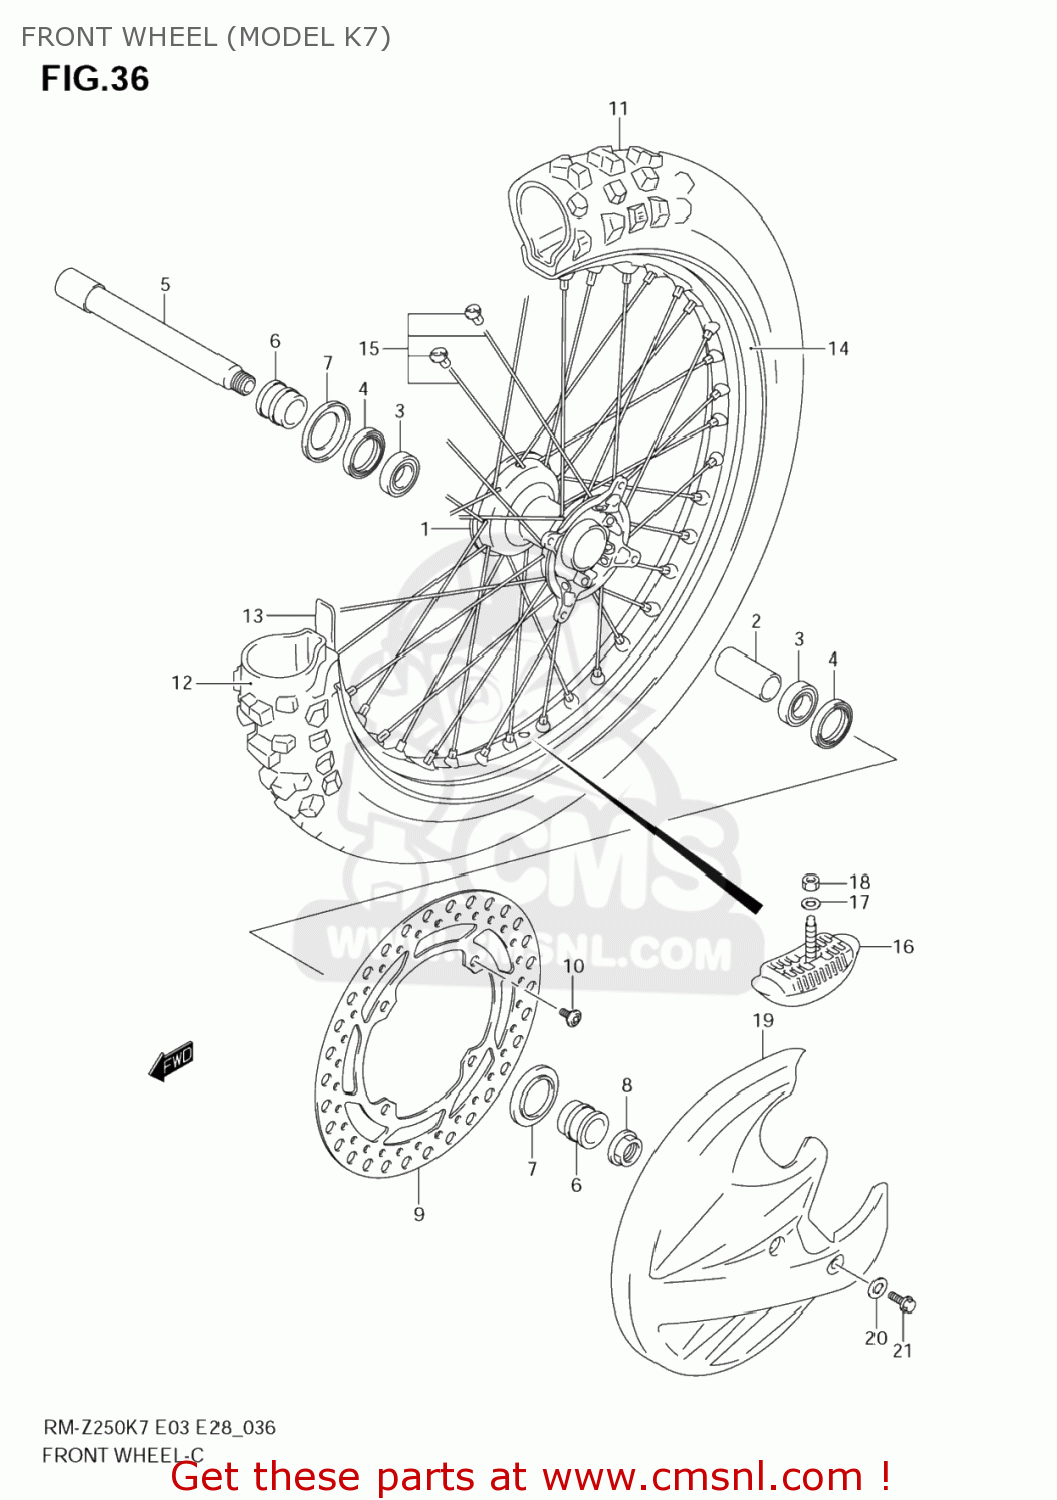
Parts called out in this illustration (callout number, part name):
1	HUB,FR
2	SPACER,FR HUB BEARING
3	BEARING(22X39X9)
4	SEAL,OIL(30X40X7)
5	AXLE,FR
6	SPACER,FR AXLE
7	COVER,FR AXLE SPACER
8	NUT
9	DISC,FR BRAKE
10	SCREW(6X13.5)
11	TIRE,FR(80/100 21)
12	TUBE ASSY,WHEEL INNER
13	PROTECTOR,WHL INR TUBE
14	RIM,FR WHEEL
15	SPOKE SET,FR WHEEL
16	STOPPER,BEAD
17	WASHER
18	NUT
19	COVER,FR BRAKE DISC
20	WASHER,FR BRAKE DISC COVER
21	BOLT(6X16)
